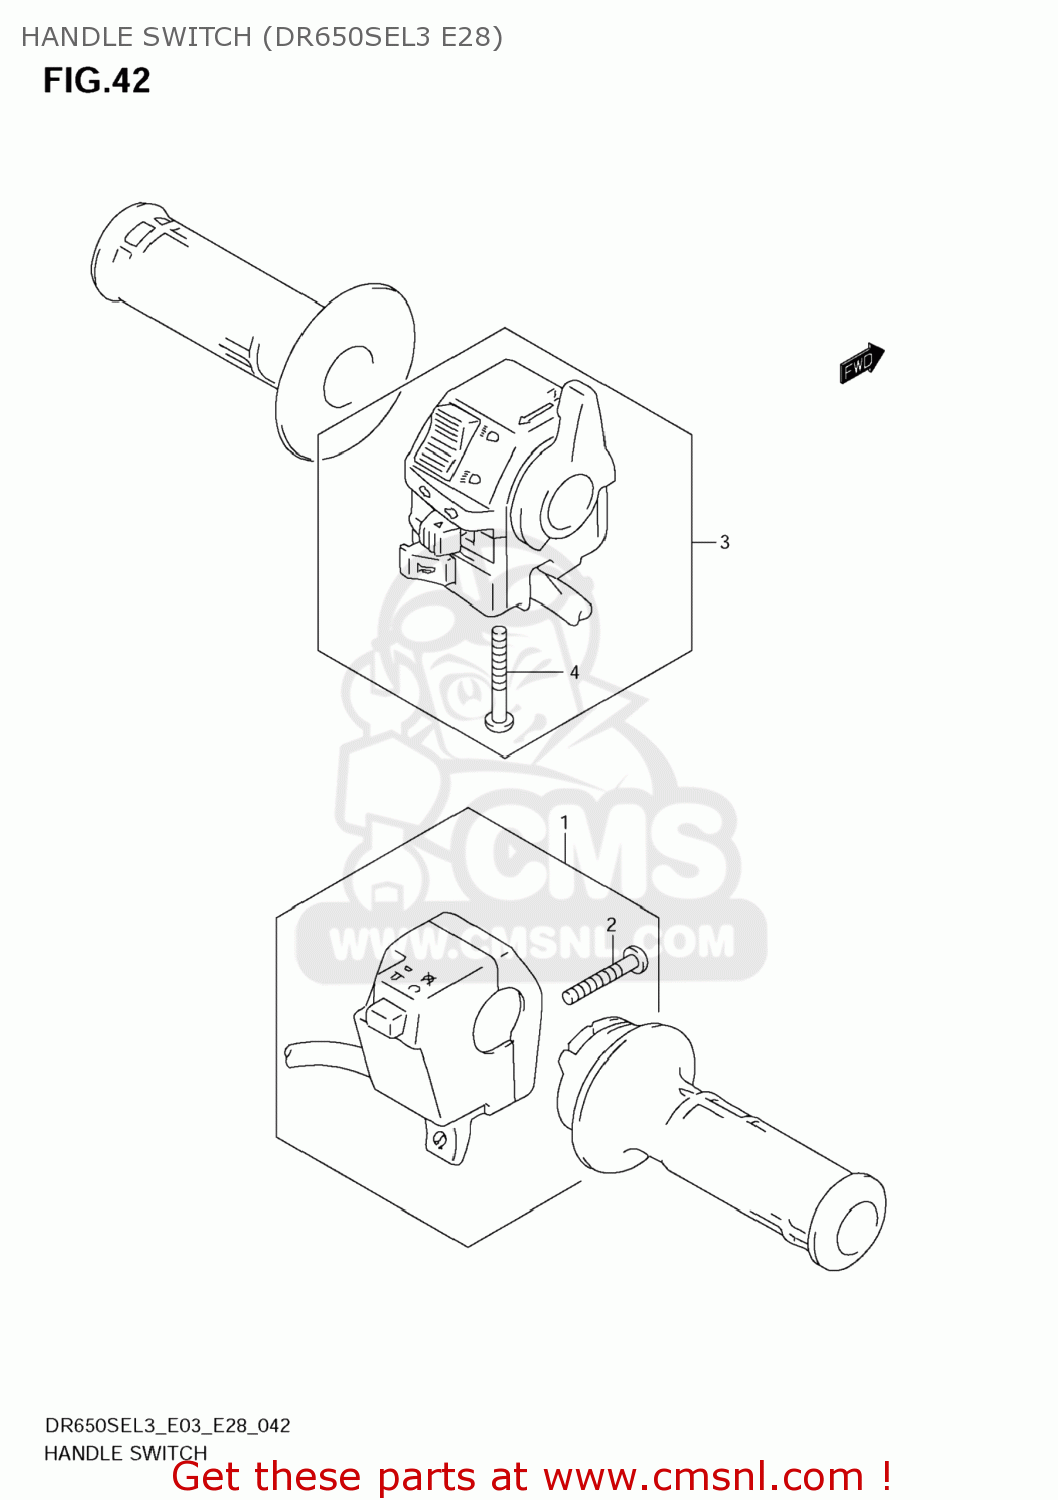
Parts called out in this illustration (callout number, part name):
1	SWITCH ASSY,HANDLE,R
2	SCREW(5X25)
3	SWITCH ASSY,HANDLE,L
4	SCREW
